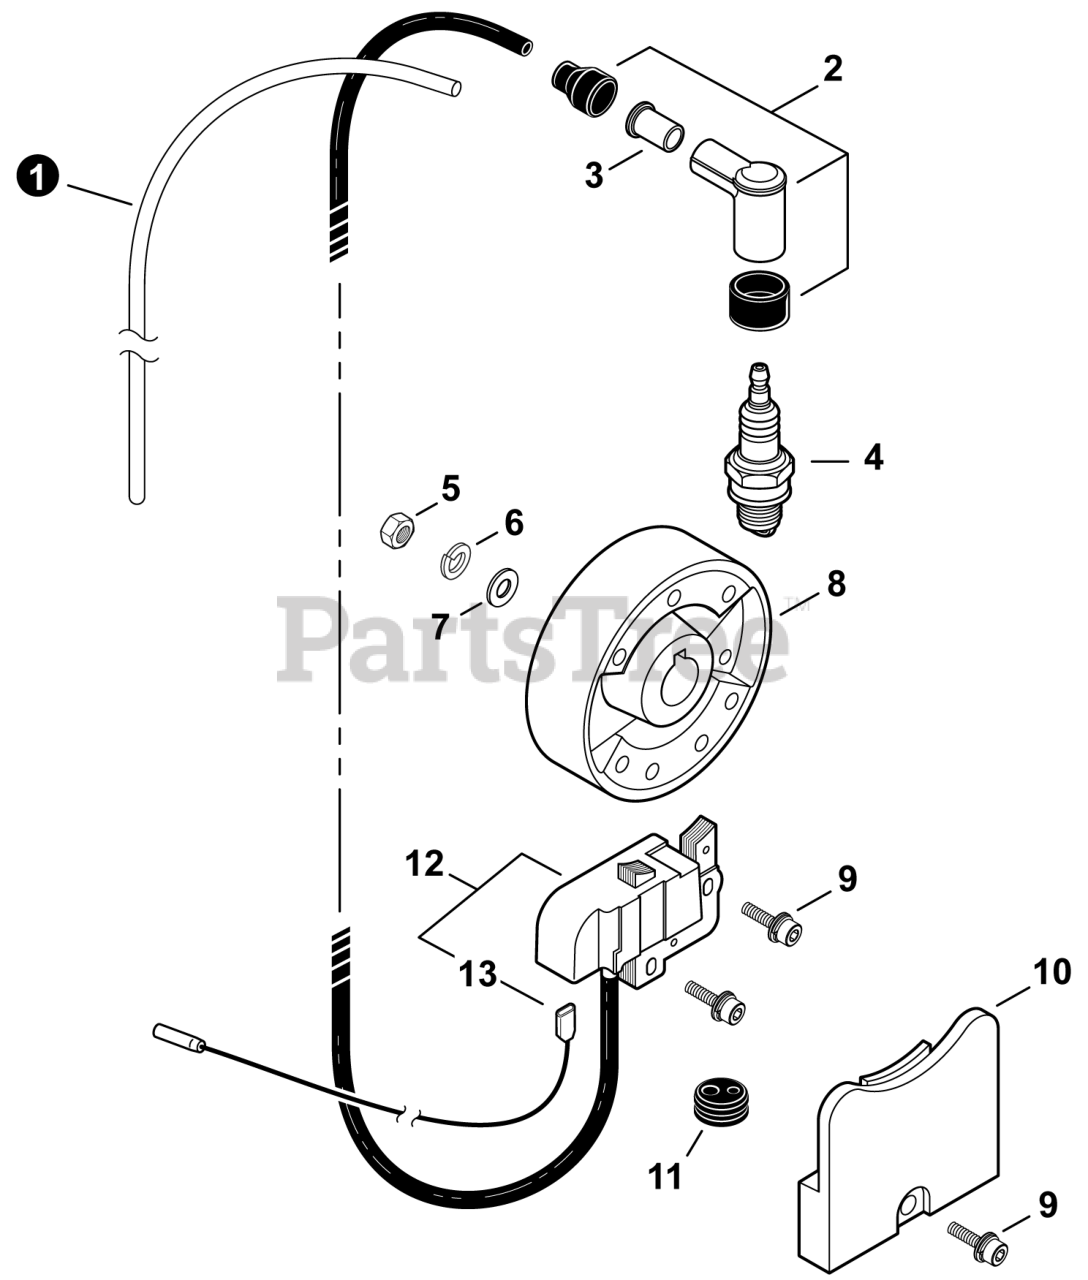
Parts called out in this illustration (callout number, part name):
1	TUBE, VINYL 6.3x8x380
2	CAP, SPARK PLUG
3	ADAPTOR, SPARK PLUG - CAP
4	SPARK PLUG - BPMR8Y
6	WASHER, SPRING 10
7	WASHER M10
8	FLYWHEEL
9	BOLT 5x22
10	COVER, DUST
12	COIL ASSY, IGNITION
13	LEAD - IGNITION
